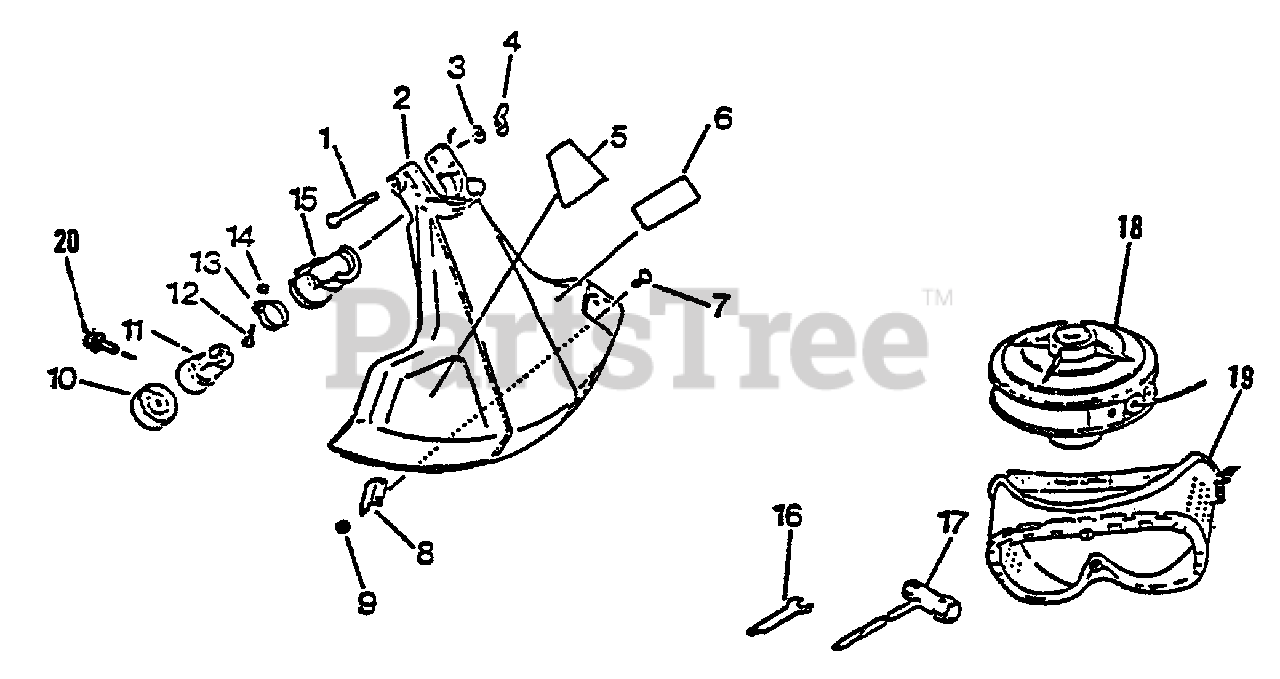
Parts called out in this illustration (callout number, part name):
1	BOLT - 6X50
2	DEBRIS SHIELD KIT
3	WASHER - 6
4	WINGNUT - 6
5	LABEL - CAUTION
6	LABEL - ECHO
7	SCREW - 5X16
8	KNIFE, TRIMMER LINE
10	ADAPTOR, BLADE - UPPER
11	GEAR CASE ASSY
12	SCREW - 5X10
15	BRACKET, BEARING CASE
16	SPANNER - 10mm
17	T-WRENCH - 8X19mm
18	KNIFE, TRIMMER LINE
20	SCREW - 4X10
